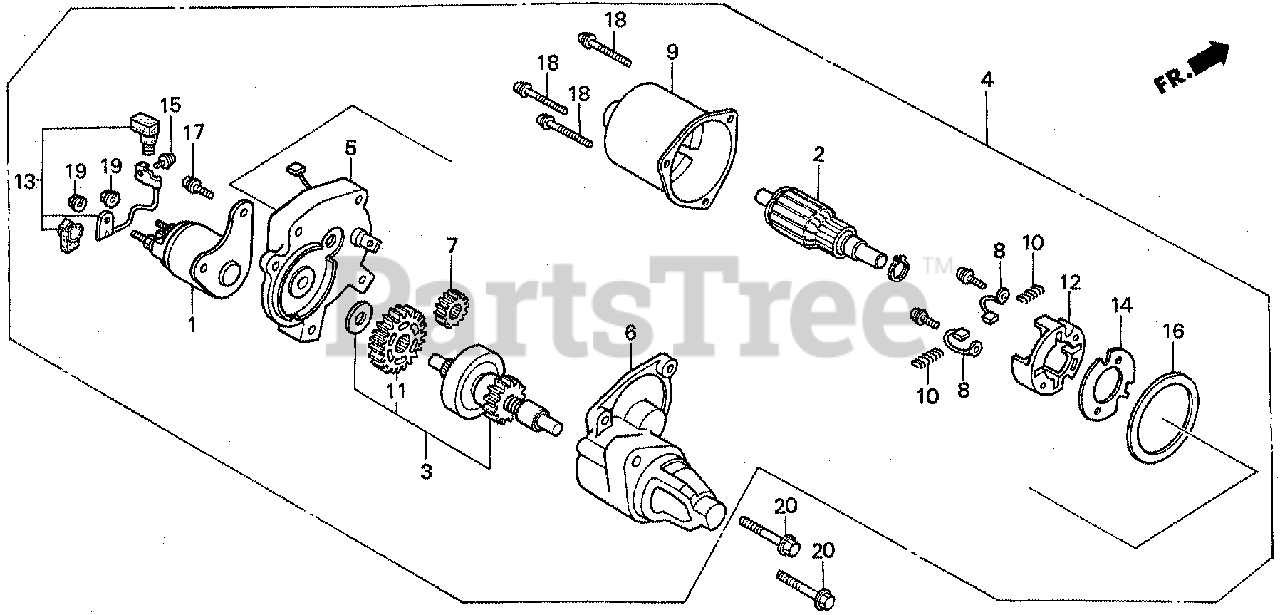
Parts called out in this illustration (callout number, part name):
1	CONTACTOR ASSY.
3	CLUTCH, OVERRUNNING
4	MOTOR UNIT, STARTER
5	BRACKET, CENTER
6	BRACKET, FR.
7	GEAR, DRIVE PINION
10	SPRING, BRUSH RETURN
11	GEAR, REDUCTION
12	HOLDER, BRUSH
13	WIRE, WATER COVER
15	SCREW-WASHER (4X6)
17	SCREW-WASHER (5X14)
18	SCREW-WASHER (5X3)
19	NUT-WASHER (6MM)
20	BOLT, FLANGE (8X35)
